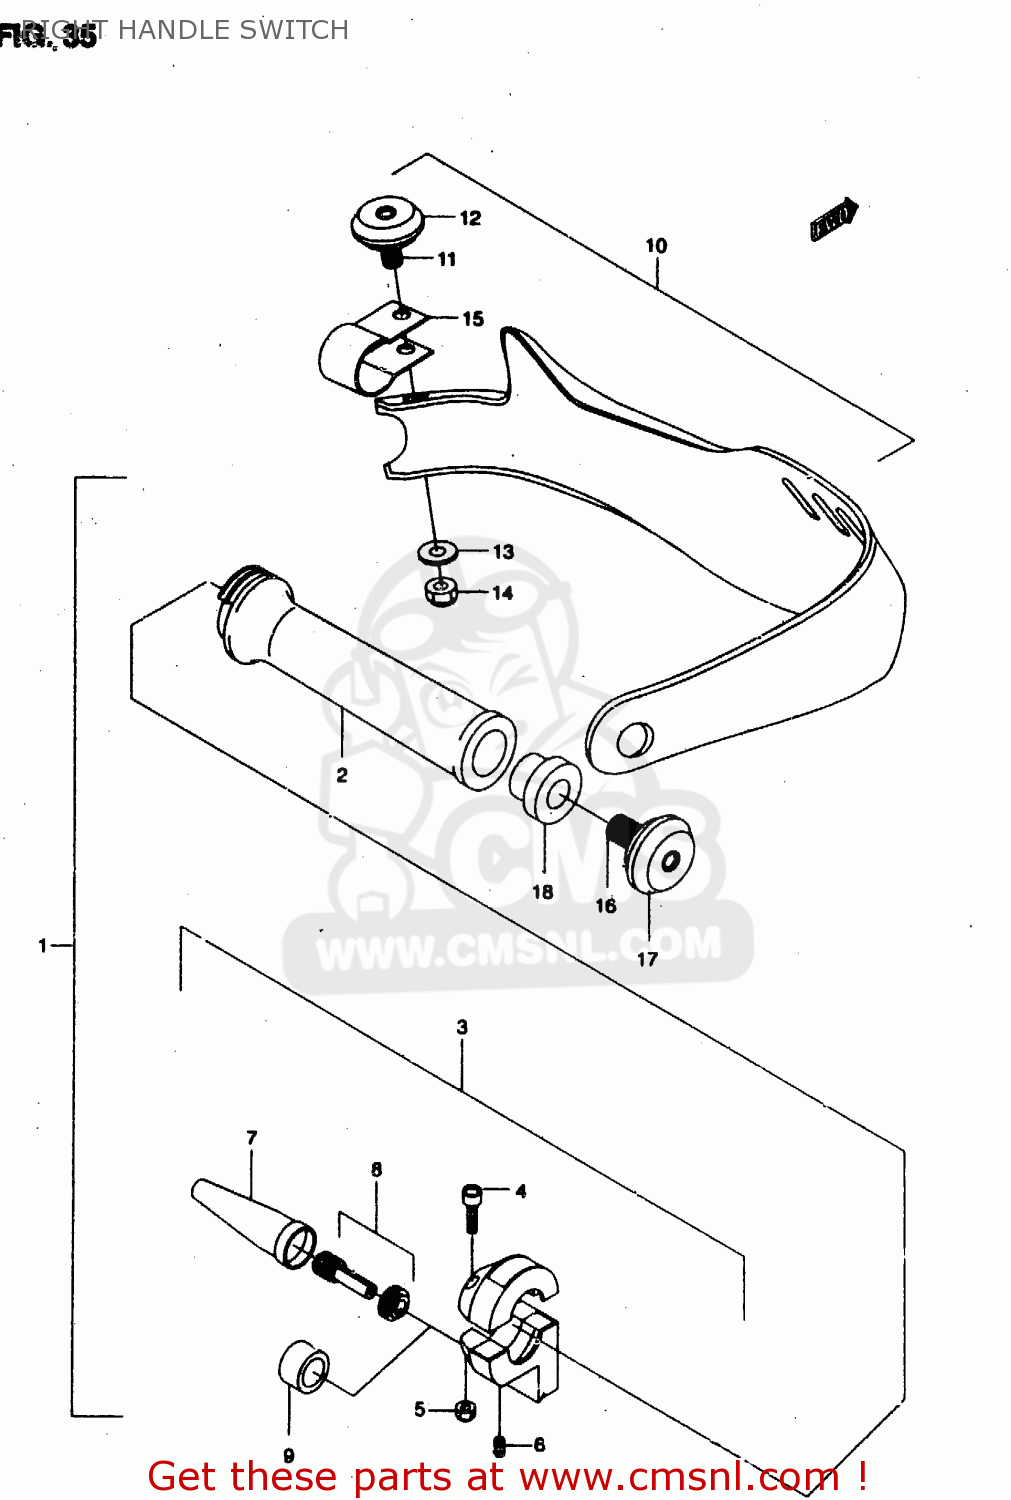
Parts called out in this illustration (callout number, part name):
1	GRIP, THROTTLE ASSY
2	GRIP, TROTTLE
3	CASE ASSY, THROTTLE
4	SCREW
5	NUT
6	BOLT
7	COVER
8	BRAKE LEVER
9	SPACER
10	COVER ASSY, KNUCKLE RH, (WHITE)
11	BOLT
12	SPACER
13	WASHER
14	NUT
15	HOLDER
16	BOLT
17	SPACER
18	NUT
